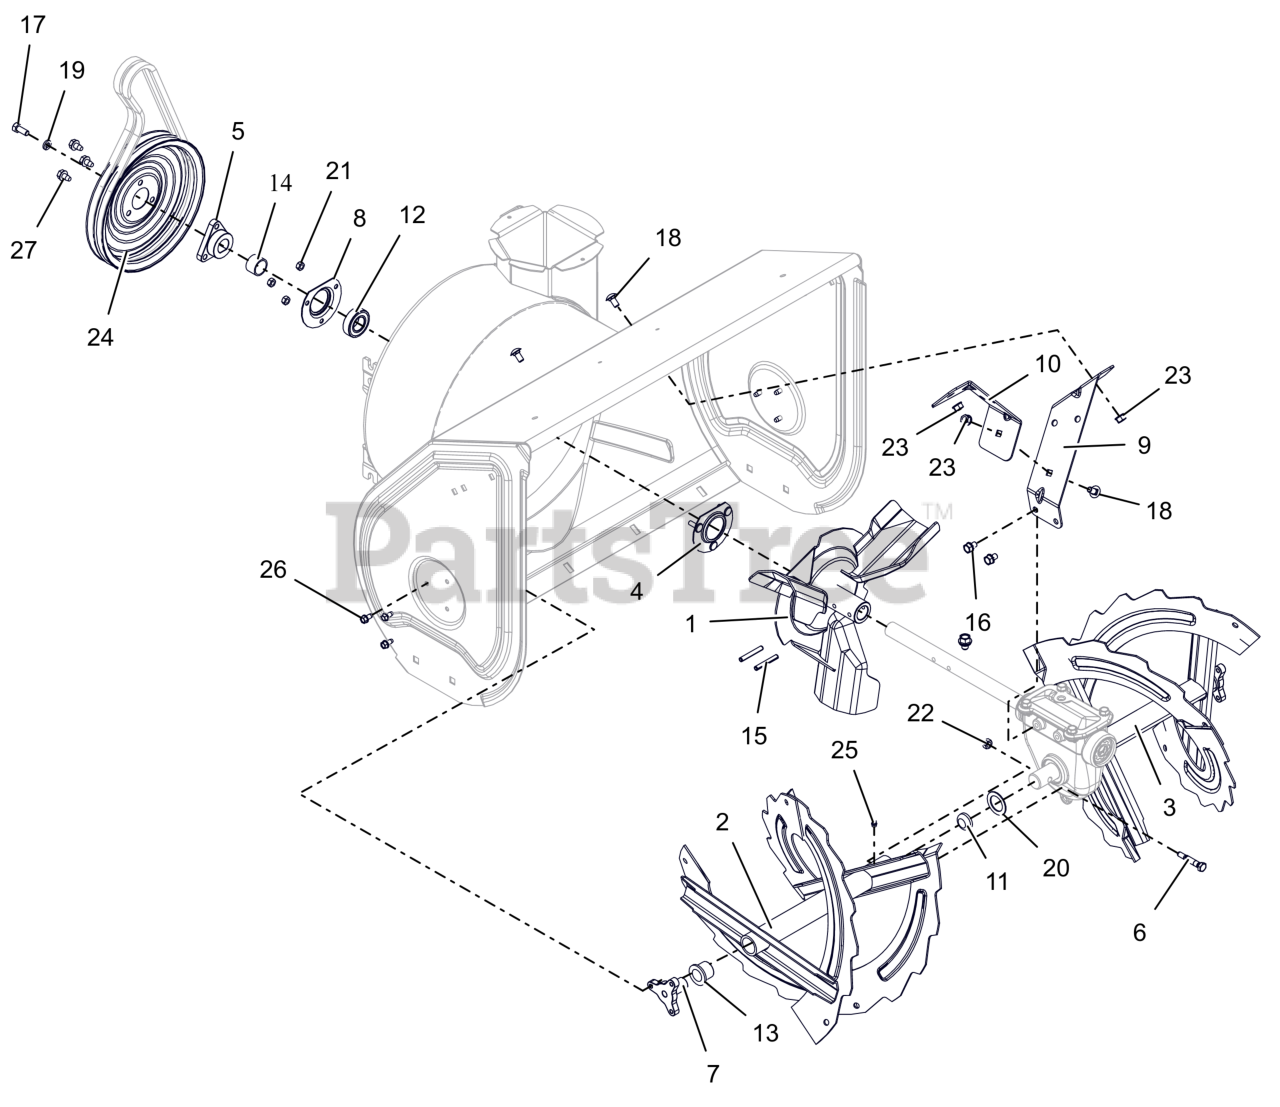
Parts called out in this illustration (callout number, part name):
1	IMPELLER, 3 BLADE-14"
2	RAKE, RH W/ZERK - 28"
3	RAKE, LH W/ZERK - 28"
4	BEARING FLANGE
5	PULLEY HUB, D-BORE .87 PRO
6	SHEAR BOLT SERVICE ASSEMBLY
7	SUPPORT, RAKE BUSHING
8	BEARING FLANGE
9	BRACKET, GEARCASE SUPPORT - LH
10	BRACKET, GEARCASE SUPPORT - RH
11	PLUG, RAKE TUBE
12	BRG-BALL .876 X 1.750 X .50
13	BSHG-FLG, NY.778 ID X 1.018 OD
14	BSHG,SPCR .895X1.065X.693
15	PIN-ROLL .250X1.75
16	BLT, SEMS .31-18X.50 G5 ZCC
17	BLT, HEX .31-24X.750 G5 ZCC
18	BLT,RHSSN.31-18X.625 G5 ZCCP30
19	WSHR, LK-HVY .312X.097 ZCC
20	WSHR, FLT 1.010X1.505X.062 ZCC
21	NUT,LK-CTR .25-20 GA ZCC
22	NUT,LK-CTR .31-18 GA ZCC
23	NUT-LK-TOP-FLG .312-18 GF ZCC
24	PULLEY, SPIN FORM DUAL GROOVE
25	ZERK,FITTING .25X.125 DRIVE IN
26	SCR-TAP .25-20X.50 HWH ZCC
27	SCR,TAP .312-18X.50 HWH TR ZCC
